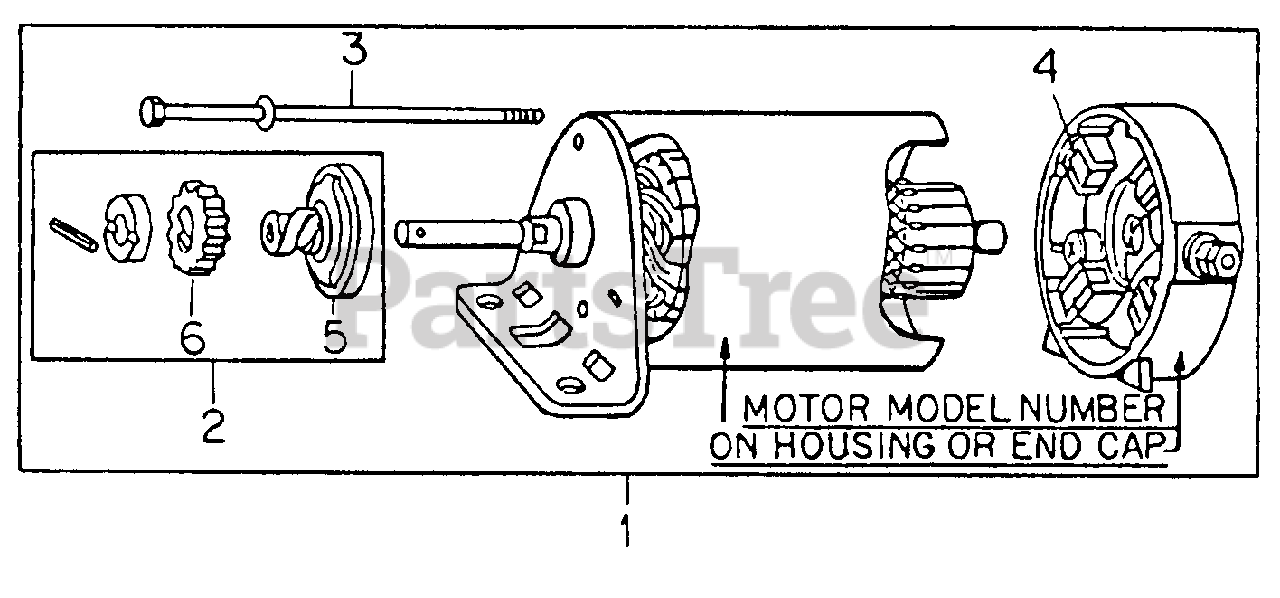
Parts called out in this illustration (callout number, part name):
1	Motor Assy, Starter - See Chart
2	Drive Assy - See Chart
3	Bolt, Thru
4	Brush Kit - See Chart
5	Drive, Starter
6	Gear, Starter Drive
